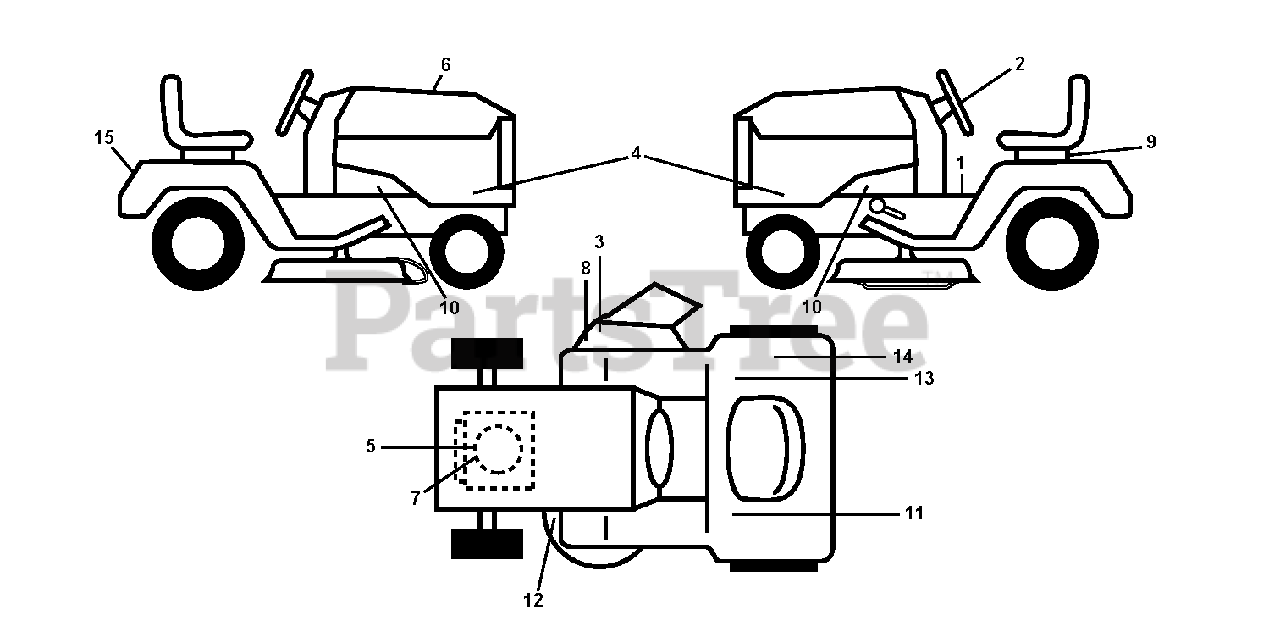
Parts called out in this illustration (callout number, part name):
3	DECAL, DEFLECT WARNING
8	DECAL.INTERNATIONL.CUTFINGER
9	DECAL BTRY SYMBOLS
12	DECAL V BELT SCHEMATIC
13	DECAL PARK BRAKE
